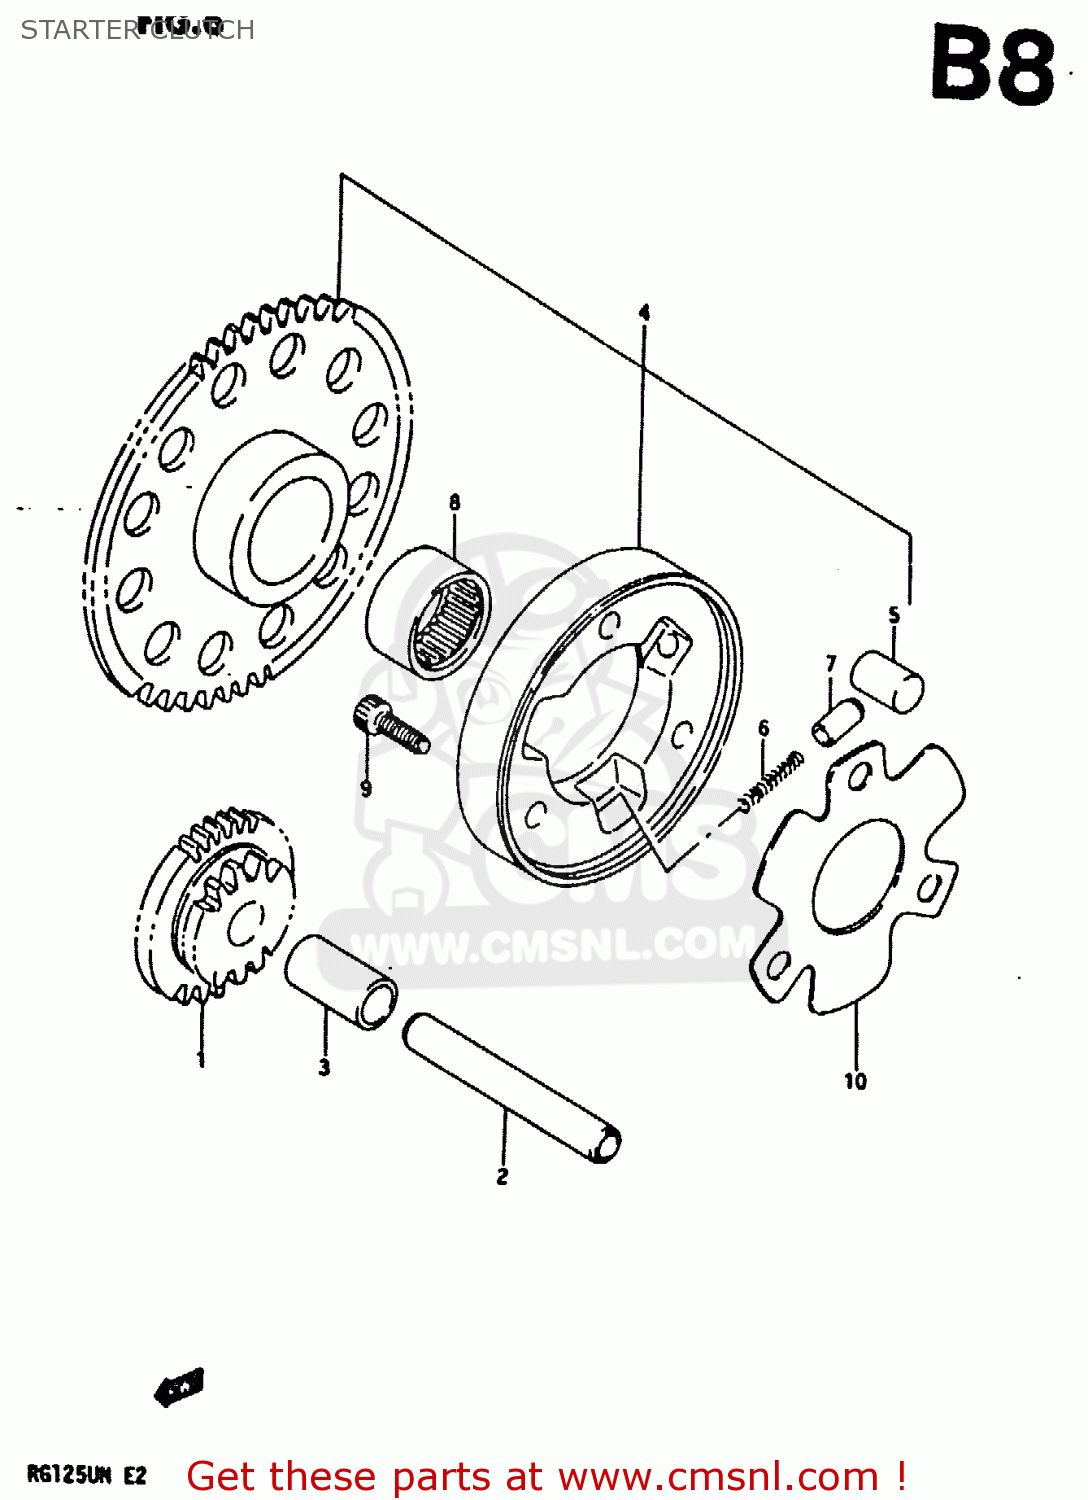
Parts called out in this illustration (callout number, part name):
1	GEAR, STARTER IDLE
2	PIN
3	SPACER
4	CLUTCH SET, STARTER
5	ROLLER(10X11)
6	SPRING
7	PIECE,STARTER CLUTCH PUSH
8	BEARING(22X28X16)
9	BOLT
10	SHIM,STARTER CLUTCH HUB
